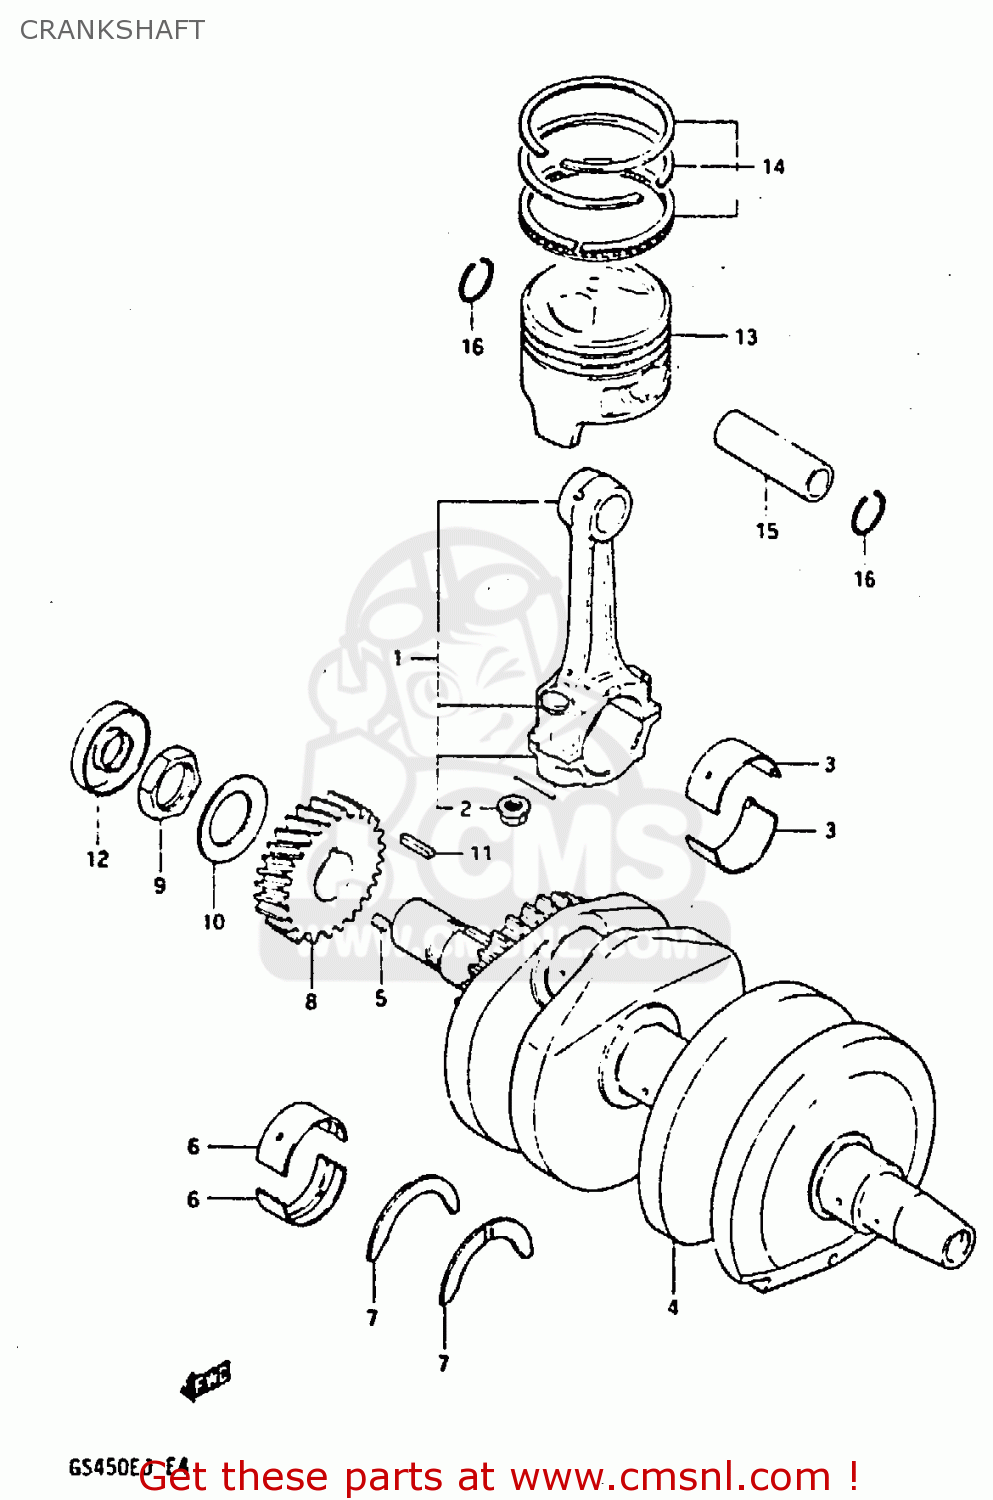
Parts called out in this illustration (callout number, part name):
1	ROD ASSEMBLY,CONNECTING
2	NUT
3	BEARING,CRANK PIN
4	CRANKSHAFT
5	PIN 3X5
6	METAL CRANKSHAFT
7	BEARING,CRANK THRUST
8	GEAR,PRIMARY DRIVE NO.28
9	NUT
10	WASHER
11	KEY
12	SEAL,OIL(22X40X8)
13	PISTON
14	RING SET,PISTON
15	PIN,PISTON (18MM)
16	CIRCLIP,PISTON PIN
